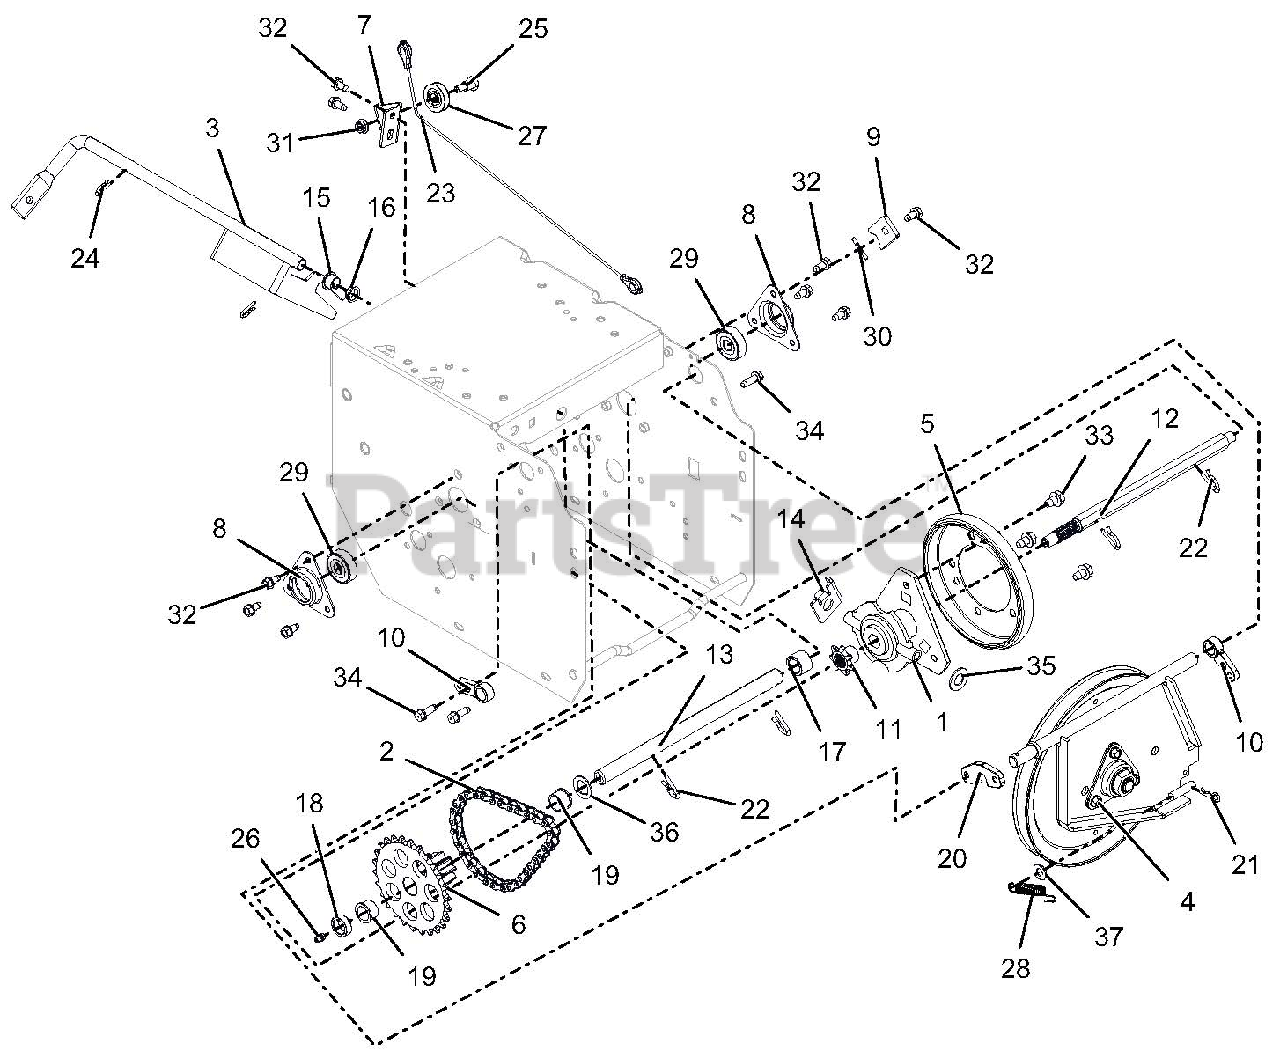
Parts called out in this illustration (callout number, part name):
1	CARRIER, DRIVE DISK
2	CHAIN - #41, 32 PITCHES
3	WELDMENT, SHIFT FORK
4	PLATE, SWING - ASSEMBLY
5	FRICTION, DISC
6	PINION & SPROCKET
7	BRACKET, CABLE PULLEY
8	FLANGE, BEARING
9	TAB, ANTI ROTATION
10	SUPPORT BUSHING, SWING GATE
11	SPROCKET, PINION 7T W/SPLINE
12	SHAFT, HEX W/SPLINE TRACK
13	SHAFT, PINION TRACK
14	BRACKET, FORMED - SHIFT FORK
15	BUSHING, POLYLINER-.50 SPLIT
16	BUSHING, POLYLINER-.50 SNAPIN
17	SPACER, .635X.880X.611
18	BSHG-SLV, .635X.880X.305
19	BSHG-FLG .625X.750X.500X.875
20	SPACER, SWING GATE
21	PIN-HAIR INT .08X.18X1.18 YWZC
22	PIN, SPRING CLIP
23	CABLE, LOWER TRACTION (CMPCT)
24	CLIP, SPRING
25	BOLT, SHLDR-.375X.375X.25-20
26	ZERK,FITTING .25X.125 DRIVE IN
27	PULLEY, CABLE
28	SPRING, EXT. .043X.438X1.64
29	BRG-BALL .437X1.375X.437
30	@PIN-GRV .125X1.00 TP E ALLOY
31	@NUT-LK-CTR-FLG .25-20 YWZC
32	SCR-TAP .25-20X.50 HWH TR YWZ
33	@SCR-TAP .31-18X.50 HWH TR YWZ
34	SCR-TAP-PM .25-20X.75 TR YWZ
35	WSHR-FL-STL .505X1.00X.062YWZC
36	WSHR-FL-STL .630X1.005X.062 YZ
37	@WSHR-FL-STL.344X.688X.065YWZC
